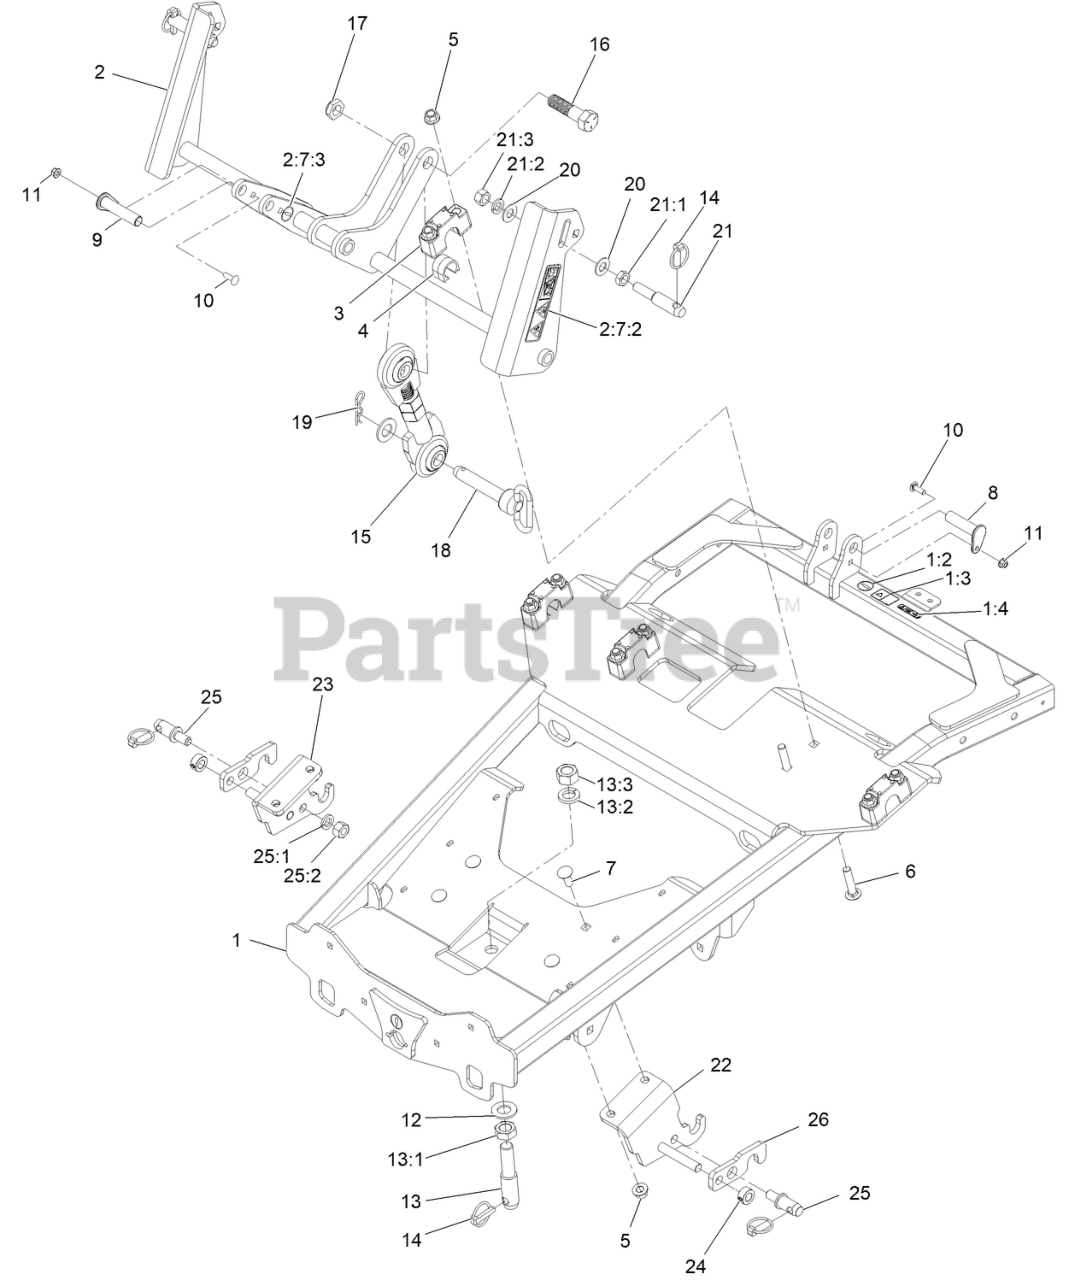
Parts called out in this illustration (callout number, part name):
1	FRONT FRAME ASM W/DECALS
1:2	DECAL-GREASE
1:3	DECAL-WARNING
1:4	DECAL-WARNING
2	Lift Arm ASM W/Decals
2:7:2	DECAL-STORED ENERGY ATTACHMENT
2:7:3	DECAL-GREASE
3	SUPPORT-CROSS SHAFT, BEARING
4	BEARING-CROSS SHAFT, FRON
5	Nut-Lock 1/2-13
6	Bolt-Carriage 1/2-13 X 2 1/2 Spl Neck
7	SCREW-CARR, SHORT NECK
9	Pin-Mounting
10	SCREW-CARR
11	NUT-HF, NI
12	WASHER-FLAT
13	1-1/8 X 5-1/4 LIFT ARM PI
13:1	NUT-JAM
13:2	WASHER-LOCK/SP
13:3	NUT-HEX
14	PIN-LYNCH
15	BALL SWIVEL, ADUSTABLE LI
16	7/8-9 X 3-1/4 GR8 HEX CAP
17	NUT-LOCK, NI
18	7/8 X 4 HITCH PIN RED HAN
19	PIN-HAIR
20	WASHER-FLAT
21	7/8 X 4-1/2 LIFT PIN\N21
21:1	NUT-JAM
21:2	WASHER-LOCK
21:3	NUT-HEX
22	X-REF 135-9471-05
23	X-REF 135-9472-05
24	5/8 SHAFT COLLAR
25	7/8 X 3-1/8 ANCHOR PIN (2
25:1	WASHER-LOCK
25:2	NUT-HEX
26	X-REF 135-9330-05
